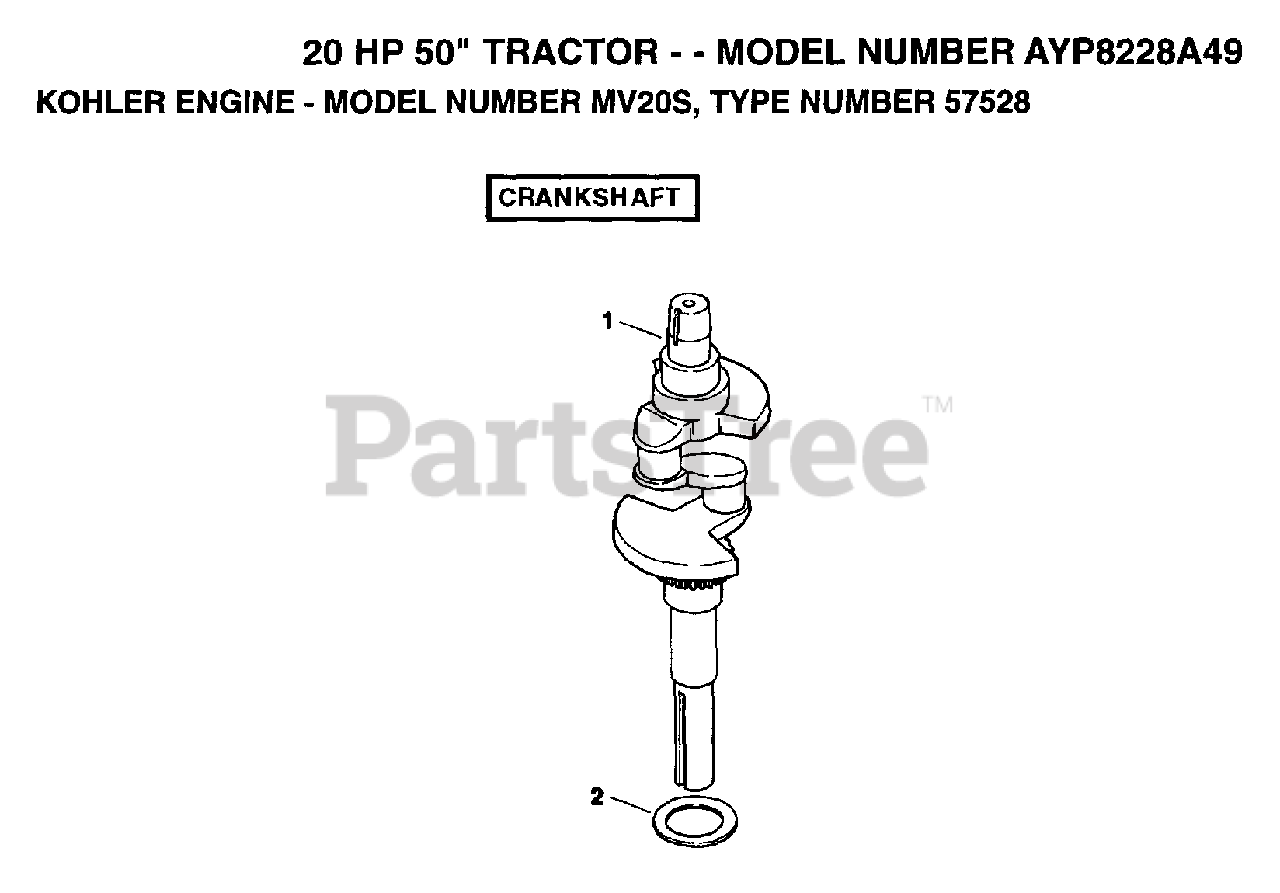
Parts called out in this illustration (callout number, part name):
2	WASHER, .119/.122 (A.R.)
2	WASHER, .128/.131
2	WASHER, .137/.140 (A.R.)
